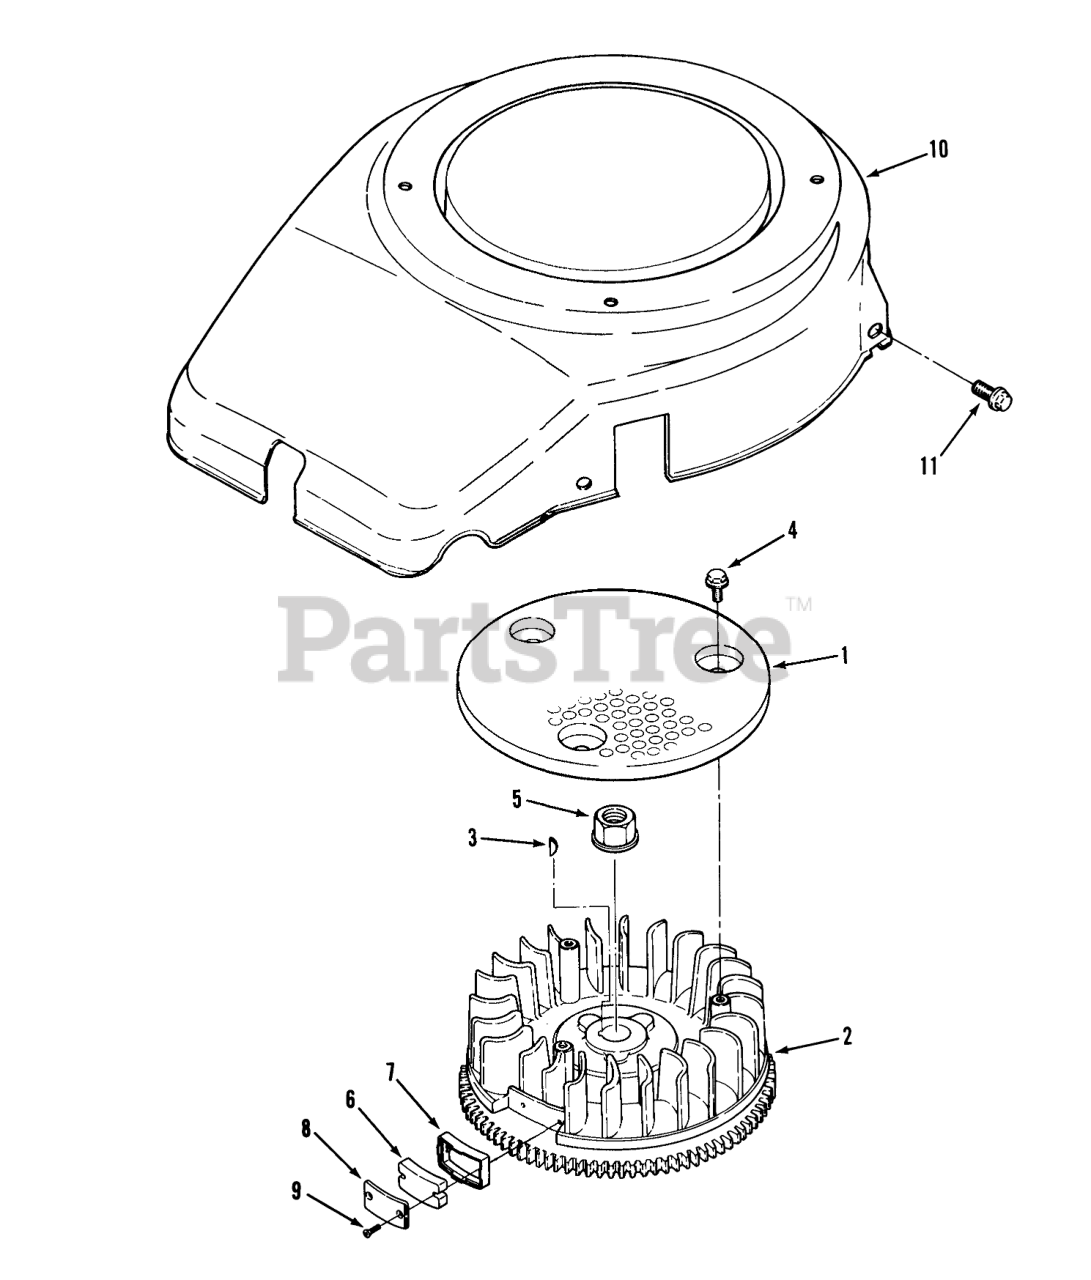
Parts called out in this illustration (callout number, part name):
1	Screen
2	WHL-ASS'Y BLOWER
4	Screw-Hex Hd.
5	NUT-FLANGE M18
6	Magnet
7	Holder
8	Cover
9	Screw
10	Blower Housing
